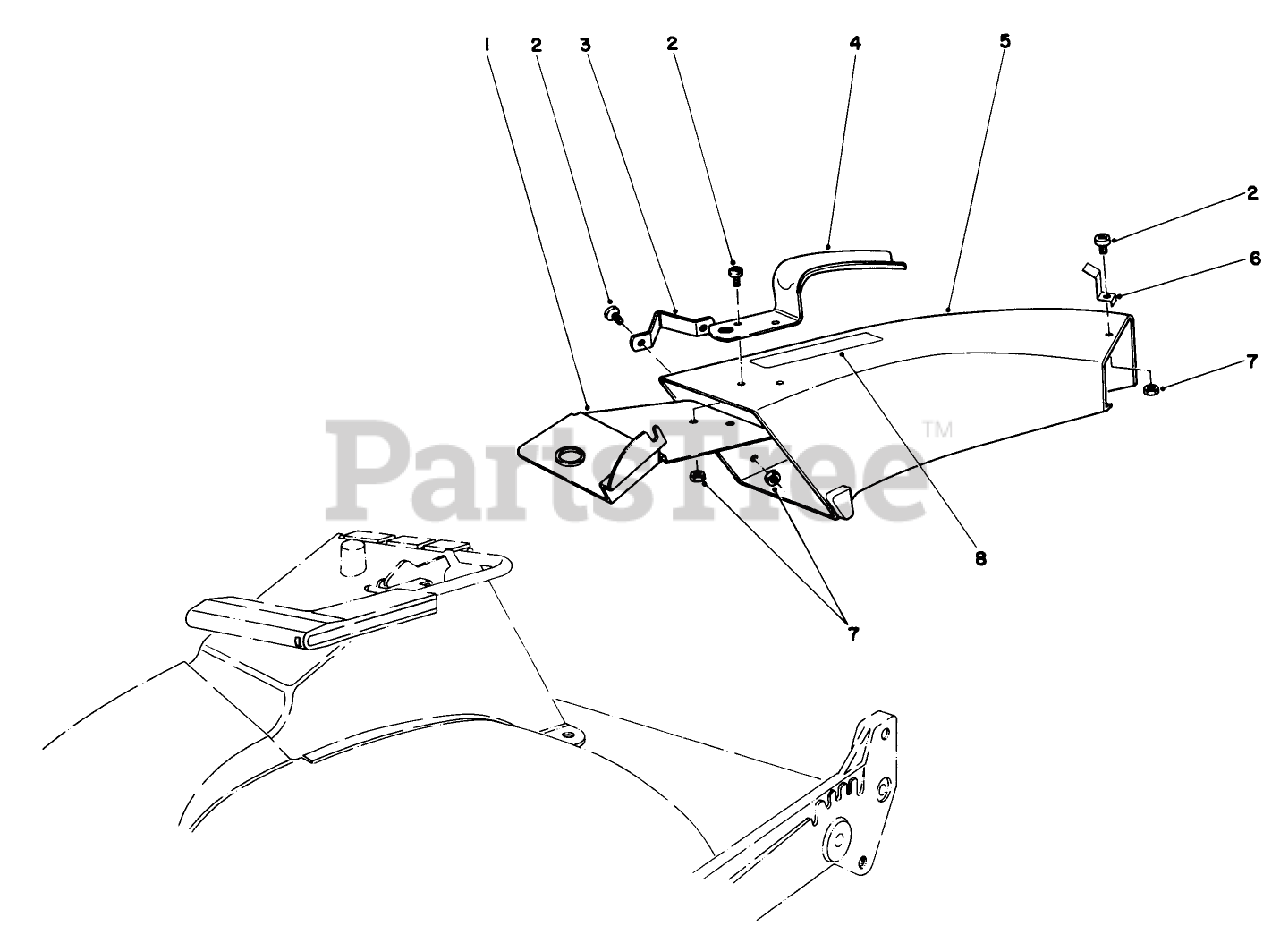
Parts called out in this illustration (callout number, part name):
2	10-24 X 5/8 PAN HD MS
4	CHUTE HANDLE
5	ORDER 59168 W.G.#
7	NUT-LOCK, NI
